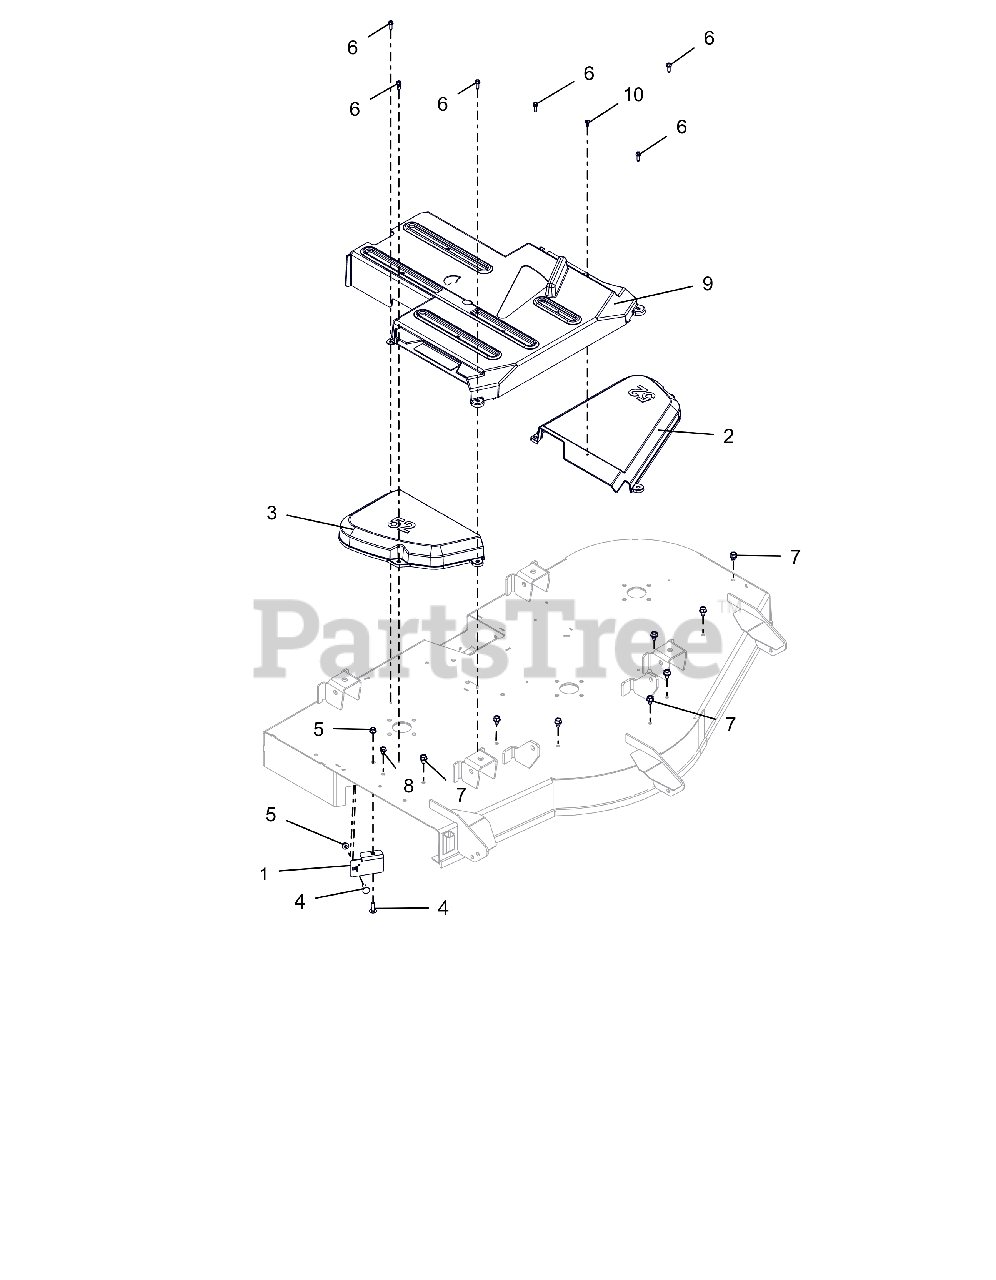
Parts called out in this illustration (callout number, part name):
1	STRIP, DEFLECTOR - 52"
2	COVER, BELT 52" LH
3	COVER, BELT 52" RIGHT
4	BLT,RHSN .31-18X1.00 G5 ZCC
5	NUT,LK-NYL-FLG .31-18 G5ZC120
6	SCR,TAP .25-20X.75 HWH TR ZCC
7	SCR,TAP .375-16X.50 HWH TR ZCC
8	SCR,TAP .312-18X.50 HWH TR ZCC
9	GUARD, CENTER, DECK
10	SCR-PAN .25-15X.50 6L H/LZB500
